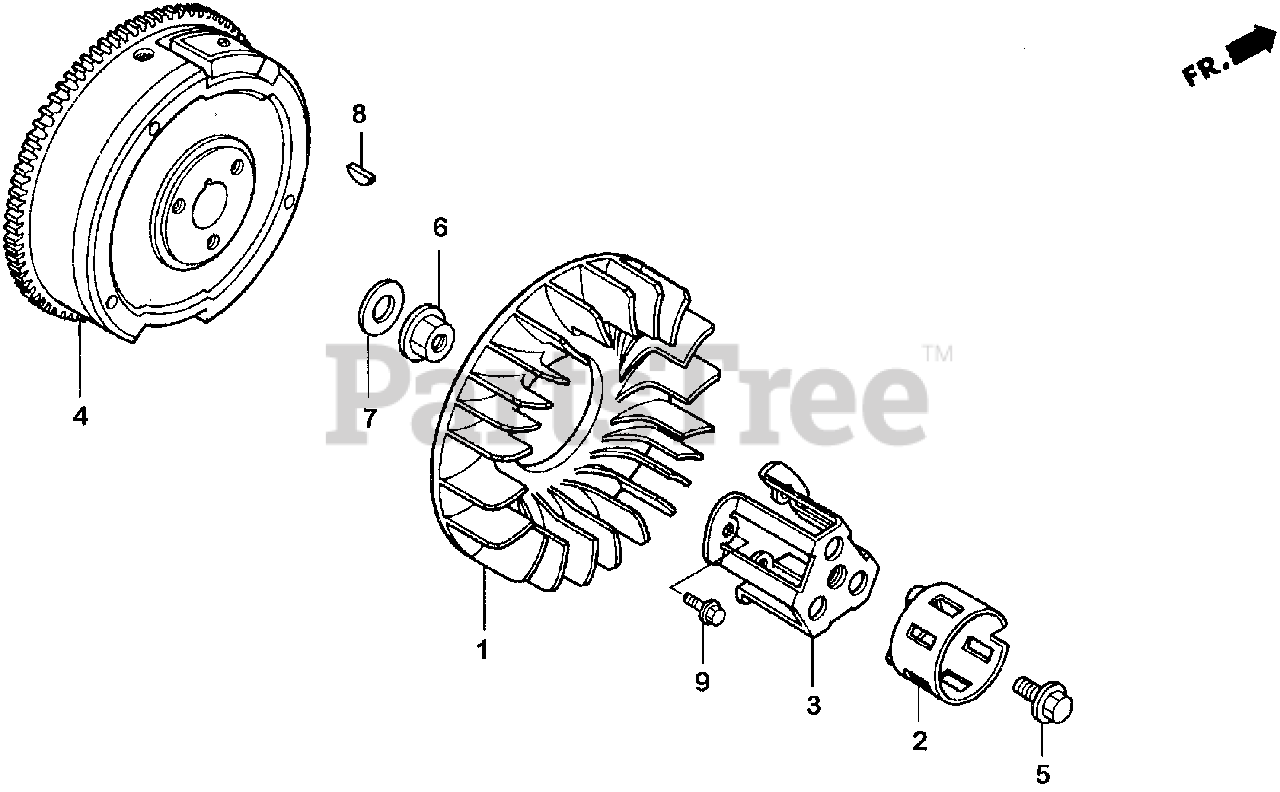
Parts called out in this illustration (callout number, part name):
1	FAN, COOLING
2	PULLEY, STARTER
3	SPACER, STARTER PULLEY MOUNTING
5	BOLT, UBS (12X28)
6	NUT, FLANGE (20MM)
7	WASHER (20MM)
8	KEY, SPECIAL WOODRUFF (25X18)
9	BOLT, FLANGE (8X16) Use from Engine SN 1000016.
